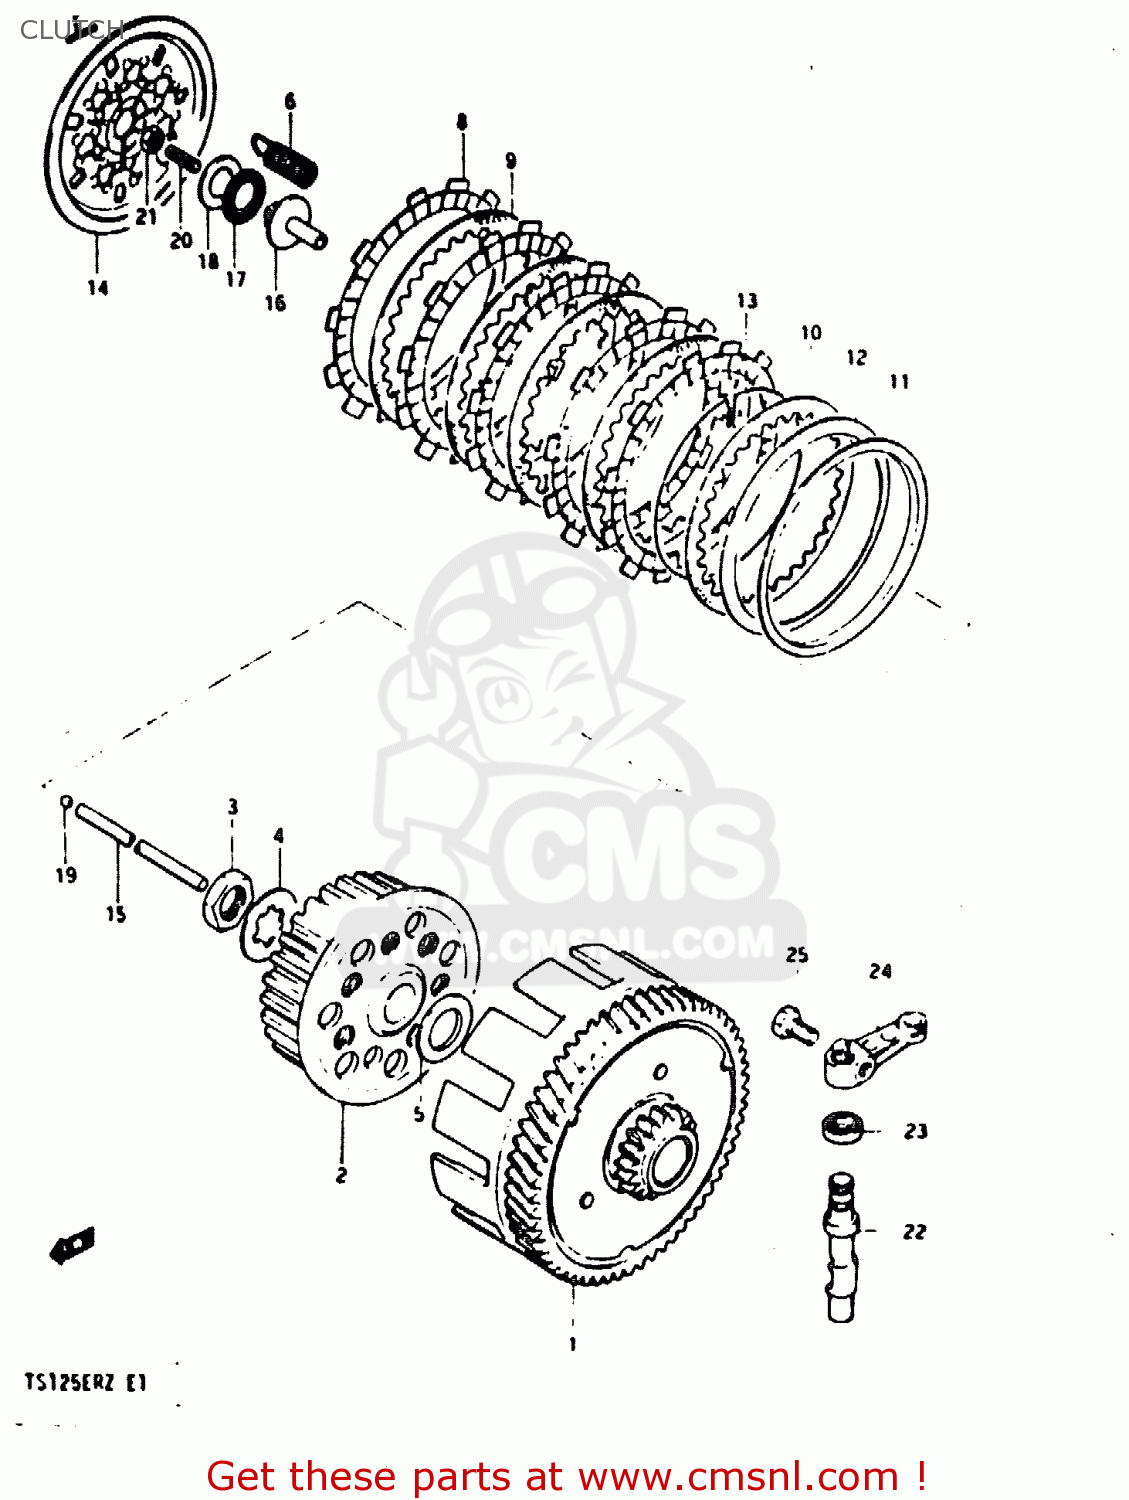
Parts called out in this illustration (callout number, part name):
1	GEAR, PRIMARY DRIVEN
2	HUB,CLUTCH SLEEVE
3	NUT
4	WASHER,LOCK
5	WASHER
6	SPRING
7	PIN(2.5X19.8)
8	PLATE,CLUTCH DRIVE
9	PLATE,CLUTCH DRIVEN (NAS)
10	PLATE,CLUTCH DRIVEN(T:2.0) (NAS)
11	SEAT,WAVE WASHER
12	WASHER
13	RING,STOPPER
14	PLATE,CLUTCH PRESSURE
15	ROD,CLUTCH PUSH
16	PIECE,CLUTCH PUSH
17	BEARING(15X28X2)
18	WASHER
19	BALL
20	SCREW(6X25)
21	NUT 6MM
22	CAMSHAFT,CLUTCH RELEASE
23	OIL SEAL
24	ARM,CLUTCH RELEASE
25	BOLT, UPPER
